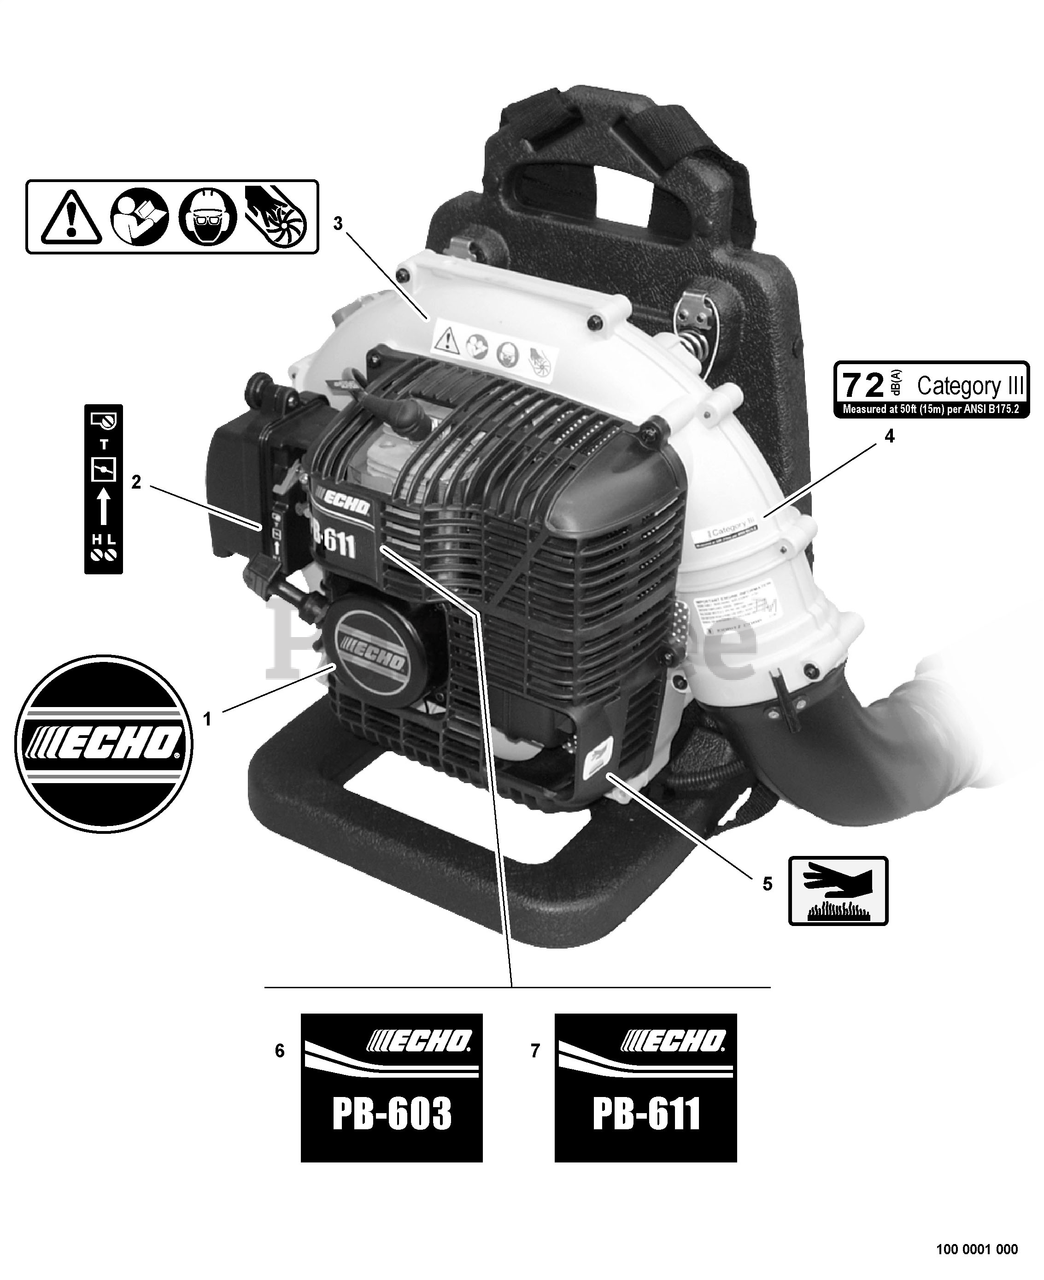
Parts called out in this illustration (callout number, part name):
1	LABEL - ECHO
2	LABEL - CHOKE
3	LABEL - CAUTION
4	LABEL - NOISE 72dB(A) CAT III
5	LABEL - HOT SURFACE
6	LABEL - MODEL PB-603
7	LABEL - MODEL PB-611
